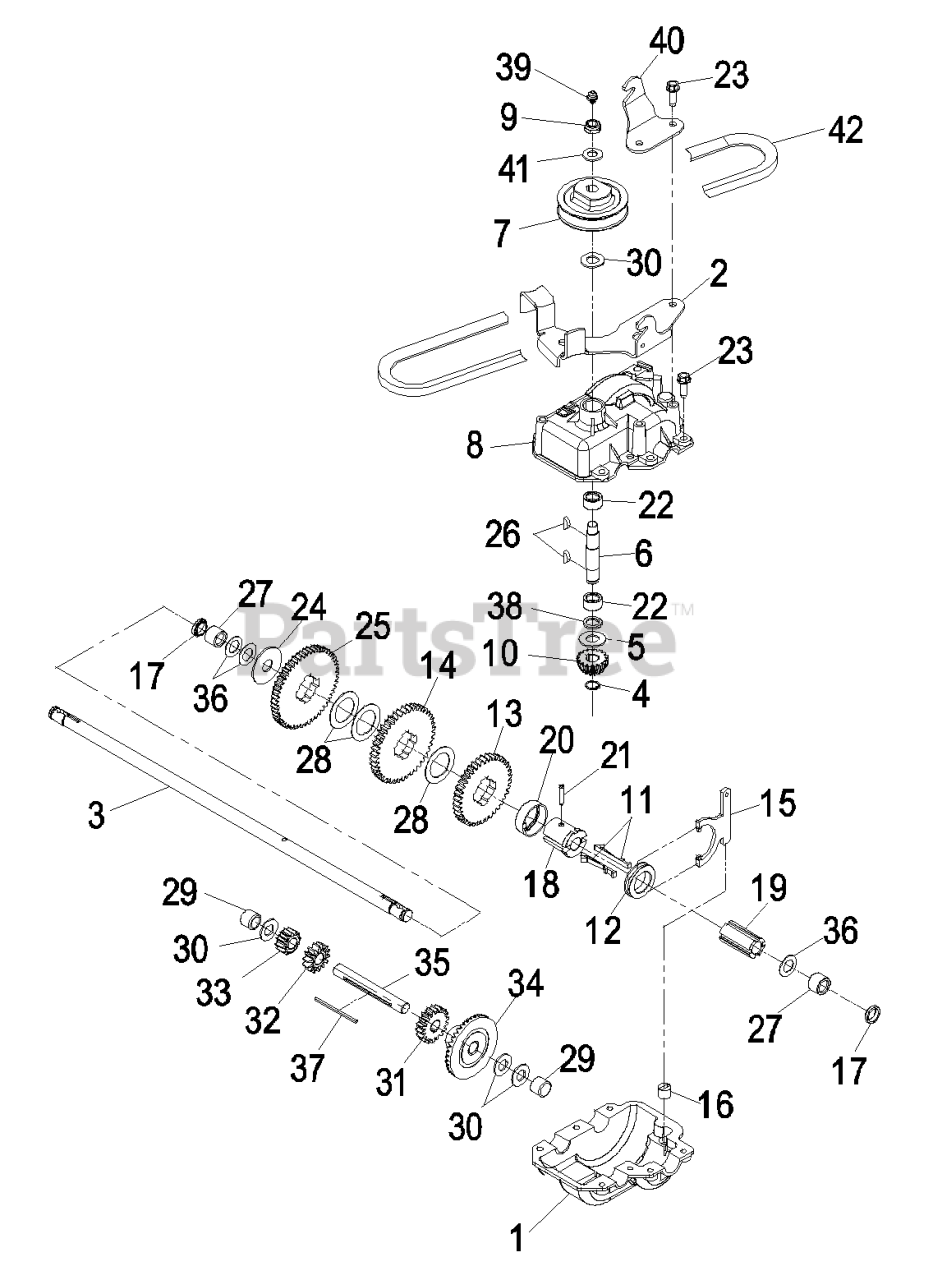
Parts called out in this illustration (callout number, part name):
2	BRACKET-GUIDE, BELT
3	SHAFT-OUTPUT
4	RING-RETAINING
5	WASHER-THRUST
9	NUT-HEX
10	PINION-BEVEL
11	KEY-SHIFT
12	COLLAR-SHIFT
13	GEAR-38T
14	GEAR-42T
15	YOKE-SHIFT
16	BUSHING-YOKE
17	SEAL-OIL
18	SLEEVE-GEAR
20	RETAINER-KEY
21	PIN-GROOVE
22	BEARING-NEEDLE
23	SCREW-HWHTF
26	KEY-WOODRUFF
29	BEARING-NEEDLE, CLOSED
30	WASHER-THRUST
31	GEAR-18T
32	GEAR-14T
33	GEAR-12T
34	GEAR-BEVEL
35	SHAFT-INTERMEDIATE
36	WASHER-PLAIN
39	FITTING-GREASE, ZERK
40	BRACKET-ENGAGE, TRACTION
41	WASHER-FLAT
42	V-BELT
